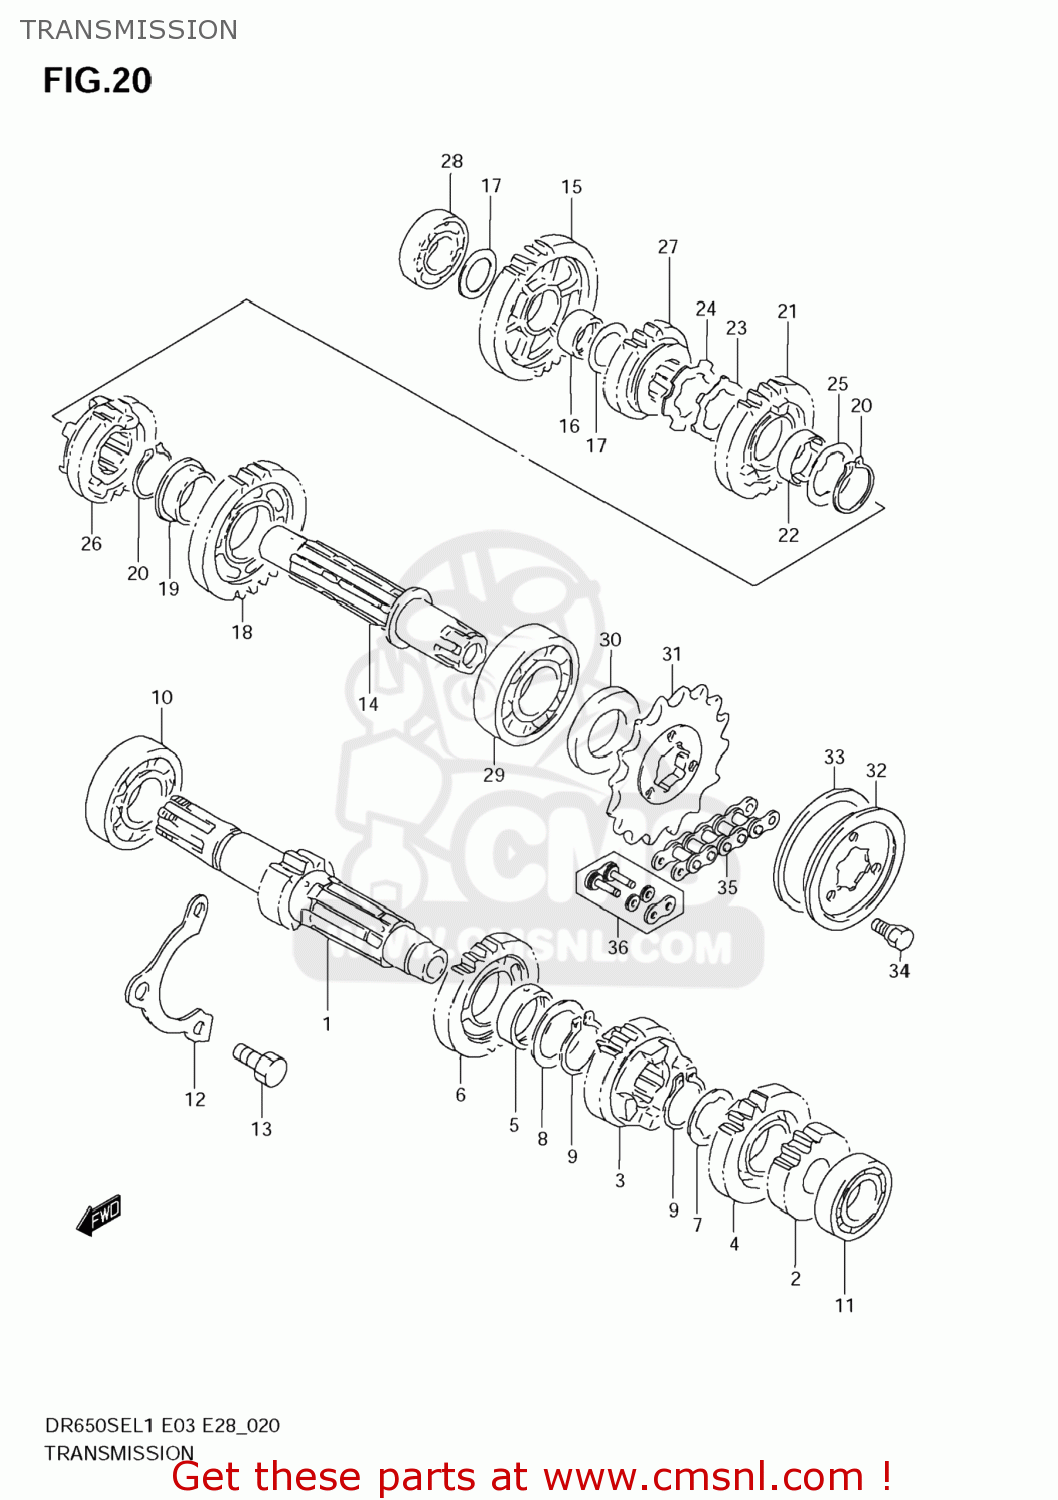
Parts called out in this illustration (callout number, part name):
1	SHAFT SET,CNTR
2	GEAR,2ND DRIVE
3	GEAR,3RD DRIVE
4	GEAR,4TH DRIVE
5	BUSH
6	GEAR,5TH DRIVE
7	WASHER,LOCK
8	SHIM(25X34X1)
9	RING,SNAP
10	BEARING(22X56X16)
11	BEARING(17X40X12)
12	RETAINER,CNTR SHAFT BEARING
13	BOLT
14	SHAFT,DRIVE
15	GEAR,1ST DRIVEN
16	BUSH(20X24X13)
17	SHIM(20X30X1)
18	GEAR,2ND DRIVEN
19	BUSH
20	RING,SNAP
21	GEAR,3RD DRIVEN
22	BUSH,DRIVEN GEAR
23	WASHER
24	WASHER,LOCK
25	WASHER,LOCK
26	GEAR,4TH DRIVEN
27	GEAR,5TH DRIVEN
28	BEARING(20X42X12)
29	BEARING(25X62X17)
30	SEAL,OIL(25X44X7)
31	SPROCKET,ENGINE(15T)
32	PLATE,ENGINE SPROCKET
33	DAMPER,ENGINE SPROCKET
34	BOLT(6X13)
35	CHAIN,DRIVE(DID525V9,110L)
36	JOINT SET,CHAIN
